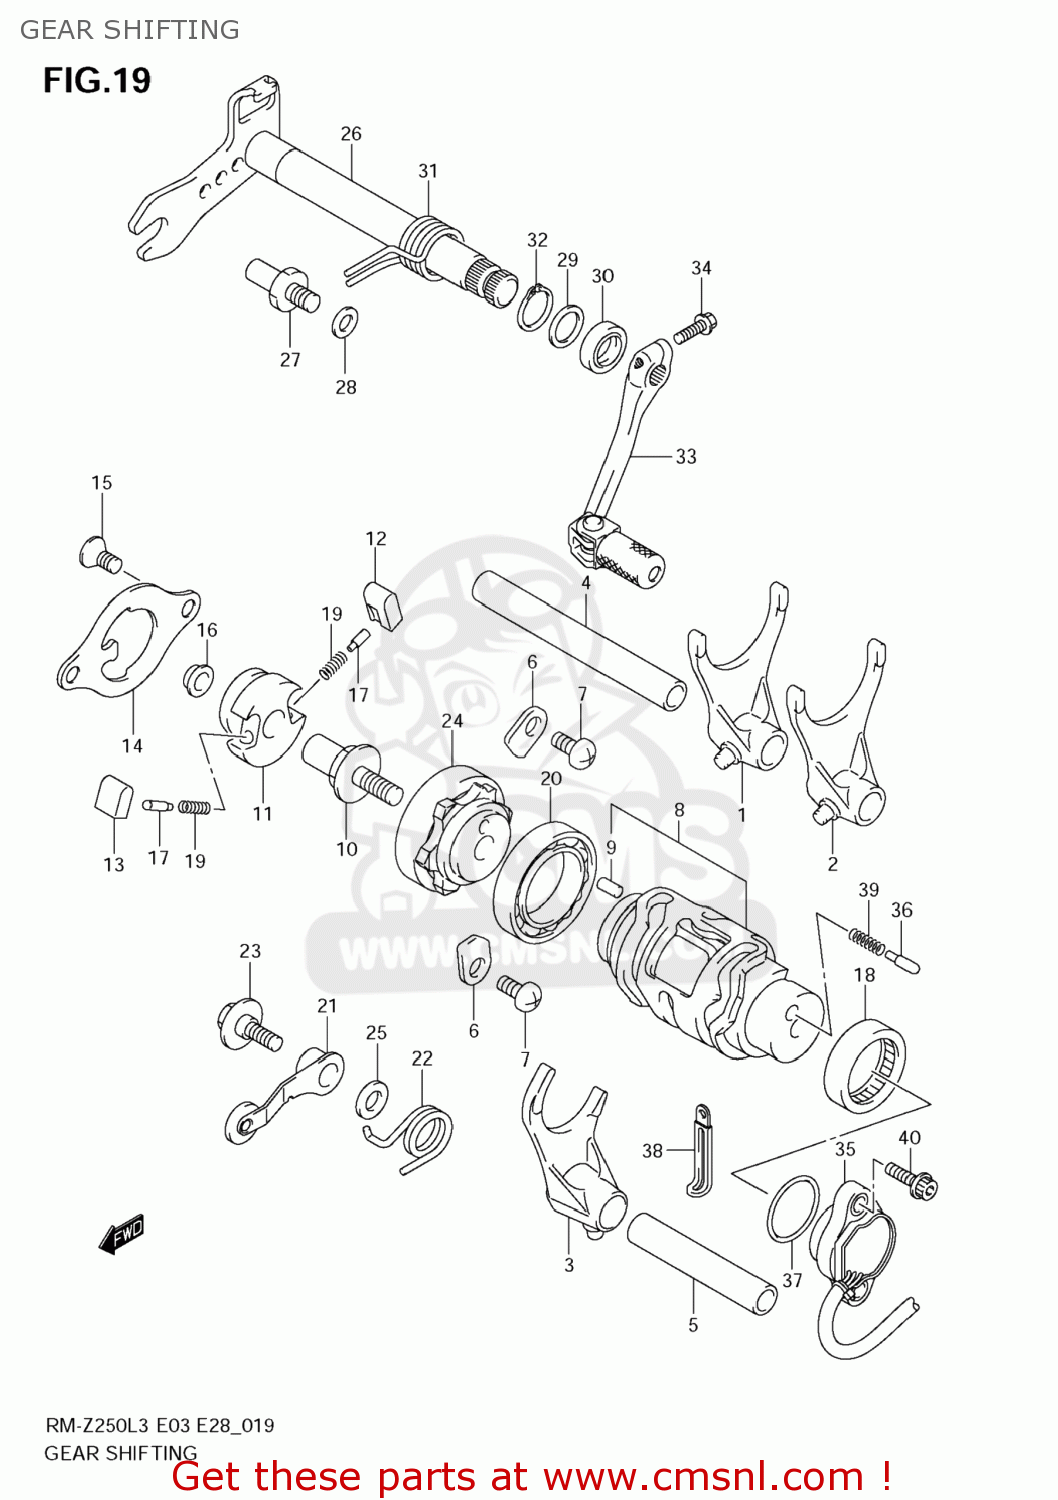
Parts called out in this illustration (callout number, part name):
1	FORK,GEAR SHIFT NO.1
2	FORK,GEAR SHIFT NO.1
3	FORK,GEAR SHIFT NO.3
4	SHAFT,GEAR SHIFT FORK(L:95)
5	SHAFT,GEAR SHIFT FORK(L:60)
6	RETAINER
7	SCREW(6X12)
8	CAM,GEAR SHIFT
9	PIN
10	PIN,GEAR SHIFT CAM
11	SHIFTER,GEAR SHIFT CAM
12	PAWL,GEAR SHIFT NO.1
13	PAWL,GEAR SHIFT NO.2
14	LIFTER,GEAR SHIFT PAWL
15	SCREW(6X12)
16	SPACER(7X10X5)
17	PIN
18	BEARING(25X32X12)
19	SPRING
20	BEARING
21	STOPPER,GEAR SHIFT CAM
22	SPRING,GEAR SHIFT CAM STOPPER
23	BOLT,SHIFT CAM STOPPER
24	PLATE,GEAR SHIFT CAM STOPPER
25	WASHER
26	SHAFT,GEAR SHIFT
27	STOPPER,GEAR SHIFT ARM
28	SHIM(8.8X14X1)
29	SHIM(14X20X1)
30	SEAL,OIL(14X22X7.3)
31	SPRING
32	CIRCLIP
33	LEVER ASSY,GEAR SHIFT
34	BOLT
35	BASE ASSY,GEAR SHIFT TERMINAL
36	PIN(5X15.5)
37	O RING(D:2.4,ID:26.2)
38	CLAMP(L:80)
39	SPRING
40	BOLT
